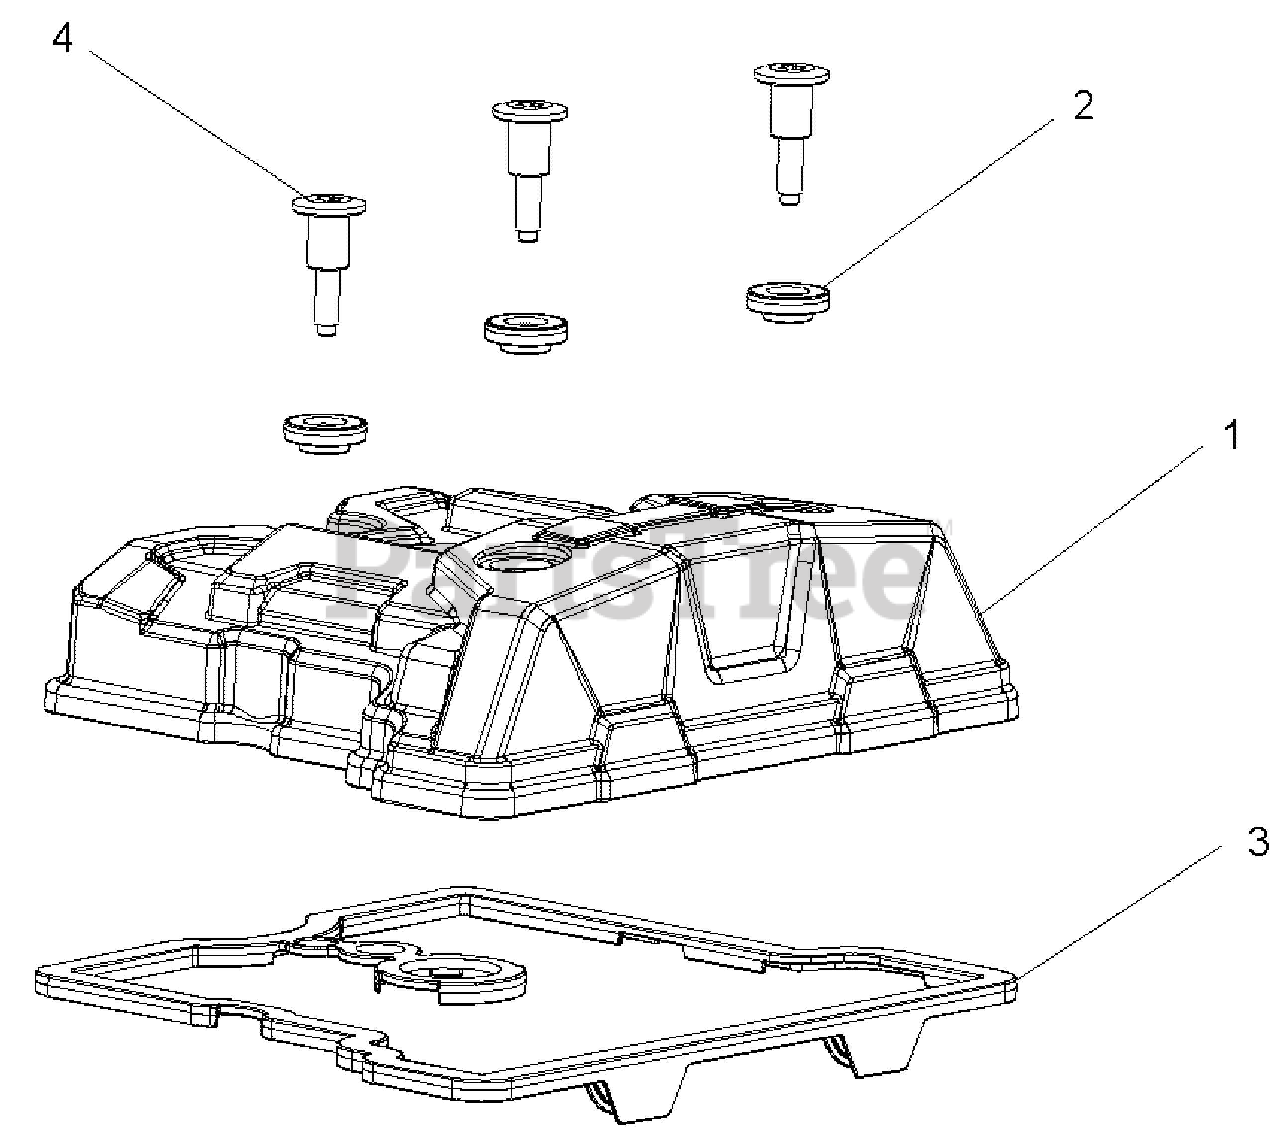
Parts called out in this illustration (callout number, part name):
1	COVER-VALVE,CAST,1CYL,DOHC
2	ISOLATOR-VALVE COVER
3	SEAL-VALVE COVER,1CYL,DOHC
4	BOLT-SHLDR,M6X12X15
